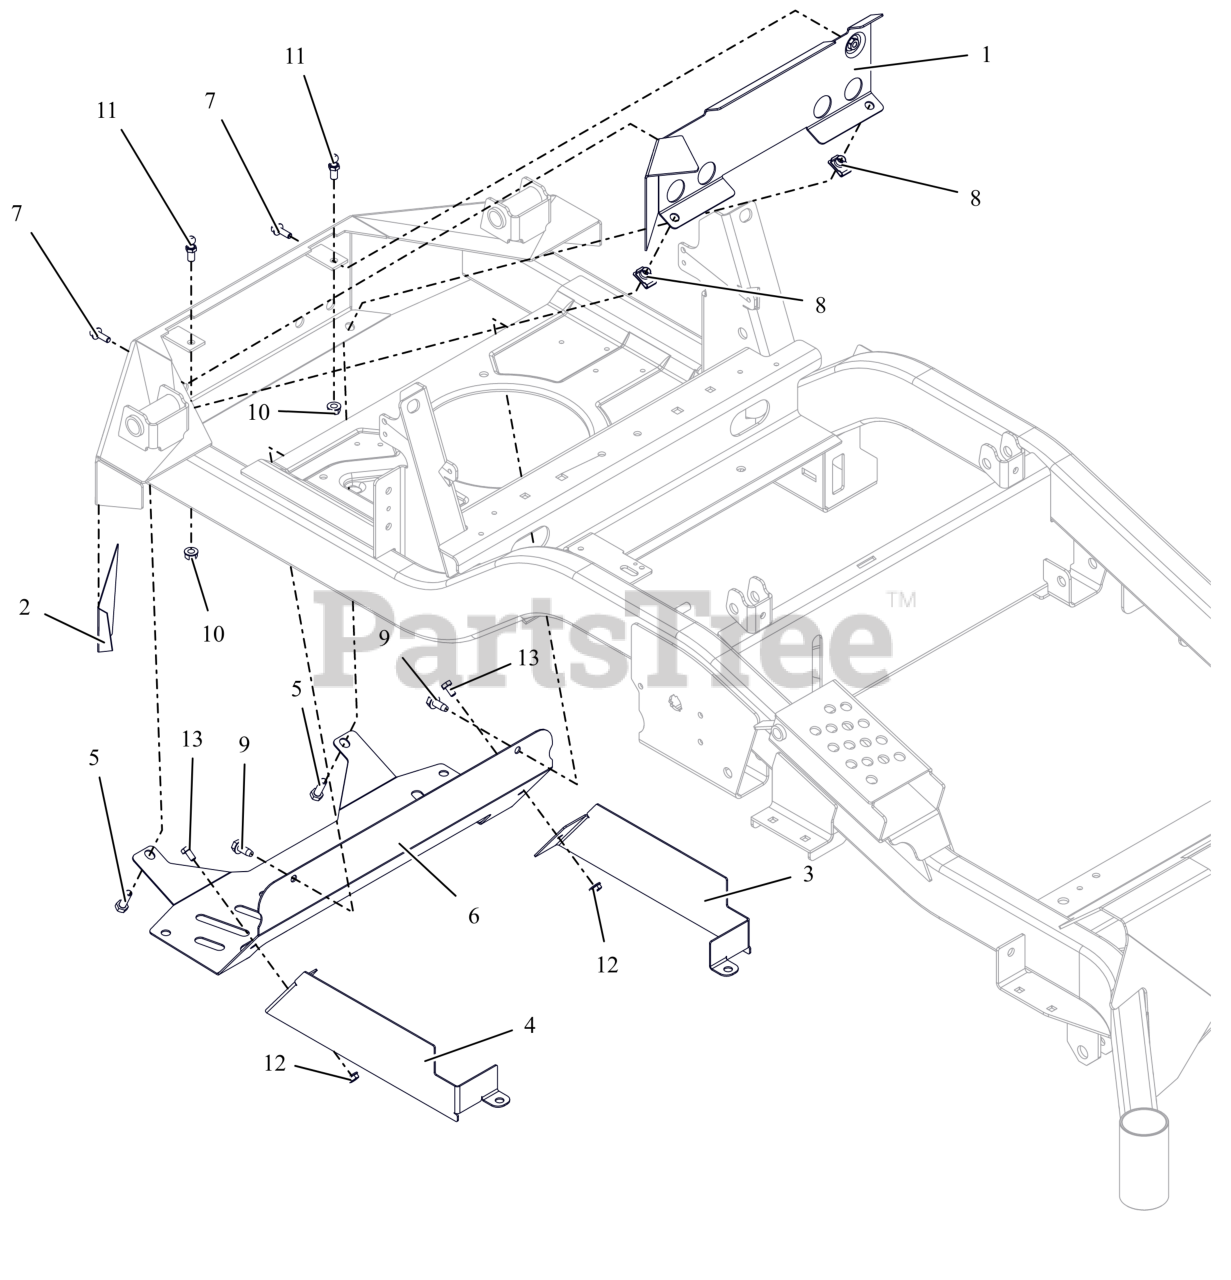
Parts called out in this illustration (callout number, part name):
1	WMT, HEAT BAFFLE
2	TAPE, HEAT DEFLECTOR
3	GUARD,REAR CLUTCH LH
4	GUARD,REAR CLUTCH RH
5	BLT,HEX .31-18X1.00 G5 ZCC
6	SHIELD, HEAT (HD)
7	BLT,HEX-FLG .25-20X.75 G5 BFP
8	NUT-CLIP RETAINER 5/16-18X.56
9	SCR,TAP .312-18X.75 HWH TR ZCC
10	NUT,LK-CTR-FLG .31-18 GF ZCC
11	STUD- BALL
12	NUT-LK-TOP-FLG .250-20 GF ZCC
13	BLT,HEX .25-20X.50 G5 ZCC
